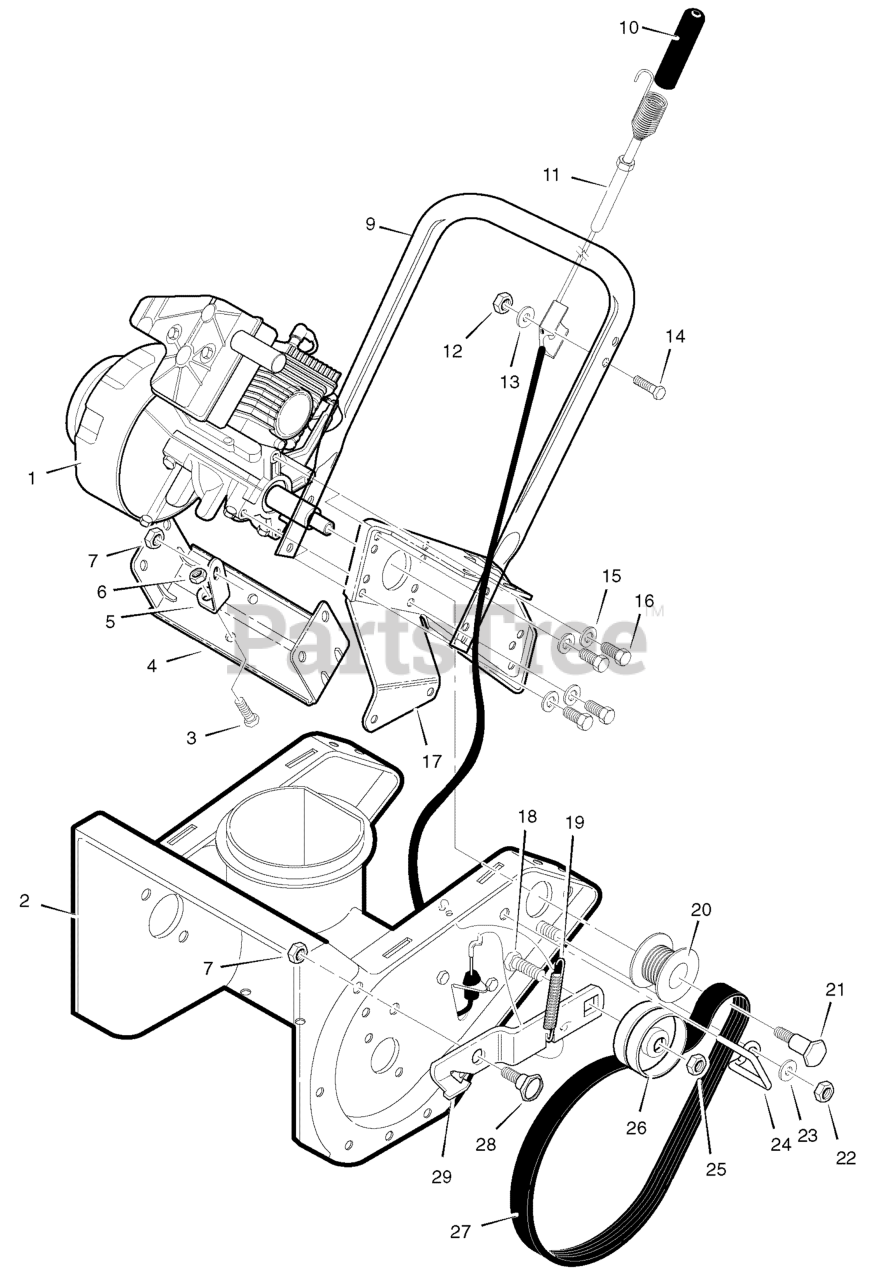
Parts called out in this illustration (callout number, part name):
1	ENGINE
2	AUGER HOUSING, 21"
3	SCREW, .31-18x .5
4	SUPPORT, FRAME
5	SUPPORT, ENGINE
6	NUT.31-18 HEX
7	NUT .31-18 HEX
9	HANDLE, LOWER
10	COVER, CABLE SPRING
11	CABLE, DRIVE
12	LOCKNUT .25-20 HEX
13	WASHER .286-0.62-.07
14	SCREW .25-20x1.50
15	WASHER .318-0.56-.05
16	SCREW, .31-18x .63
17	PLATE, REAR
18	BOLT, CARRIAGE .38-16x1.50
19	SPRING, IDLER BRAKE
20	PULLEY, 4.5 HP
21	BOLT, SHOULDER .625x.280
22	NUT.31-18 HEX
23	WASHER, FLAT .312X .73X.065
24	GUIDE, BELT
25	JAM NUT.38-16 HEX
26	PULLEY, IDLER
27	BELT, POLY-V 10 RIB 35.14
28	BOLT, SHOULDER
29	BRACKET, IDLER ARM
